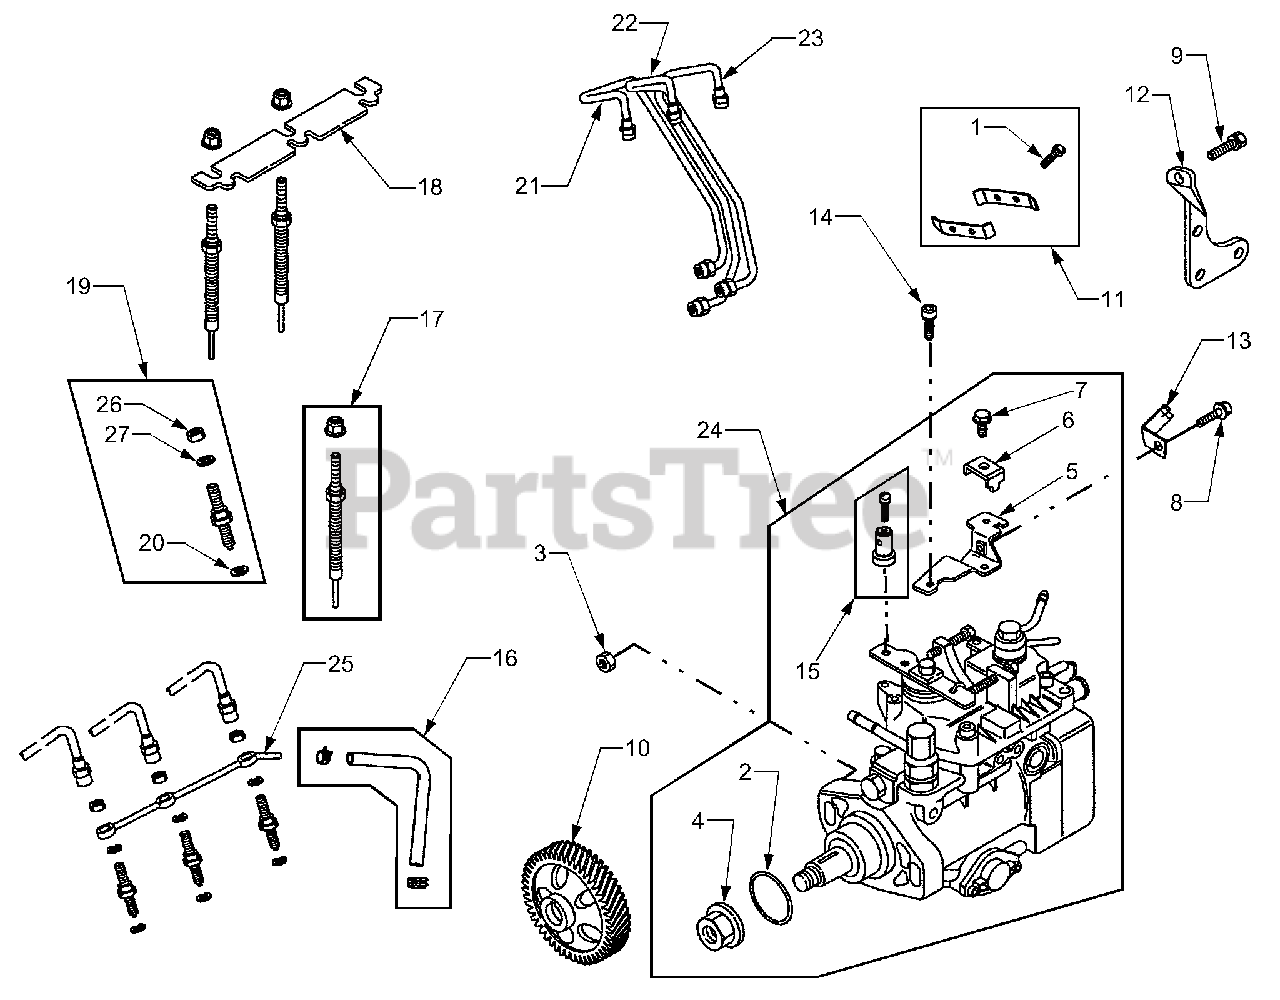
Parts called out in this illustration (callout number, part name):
1	Screw, Hex, 6mm
2	Seal, O-Ring
3	Nut, Hex Metric
4	Nut, Hex Metric
5	Bracket, Casing Clamp
6	Clamp, Casing
7	Screw, Casing Clamp
8	Screw, Support Bracket
9	Screw, Support Bracket
10	Gear, Drive
12	Bracket, Support
13	Bracket, Support
14	Screw, Casing Clamp Bracket
15	Clamp, Swivel
16	Hose/Clamp Ass’y., Fuel Return
17	Plug, Glow
18	Strap, Glow Plug
19	Nozzle, Injector
20	Seat, Injector
21	Pipe, Injector #1
22	Pipe, Injector #2
23	Pipe, Injector #3
24	Pump, Injection
25	Pipe, Fuel Return
26	Nut, Hex Injector Nozzle
27	Washer, Injector Nozzle
